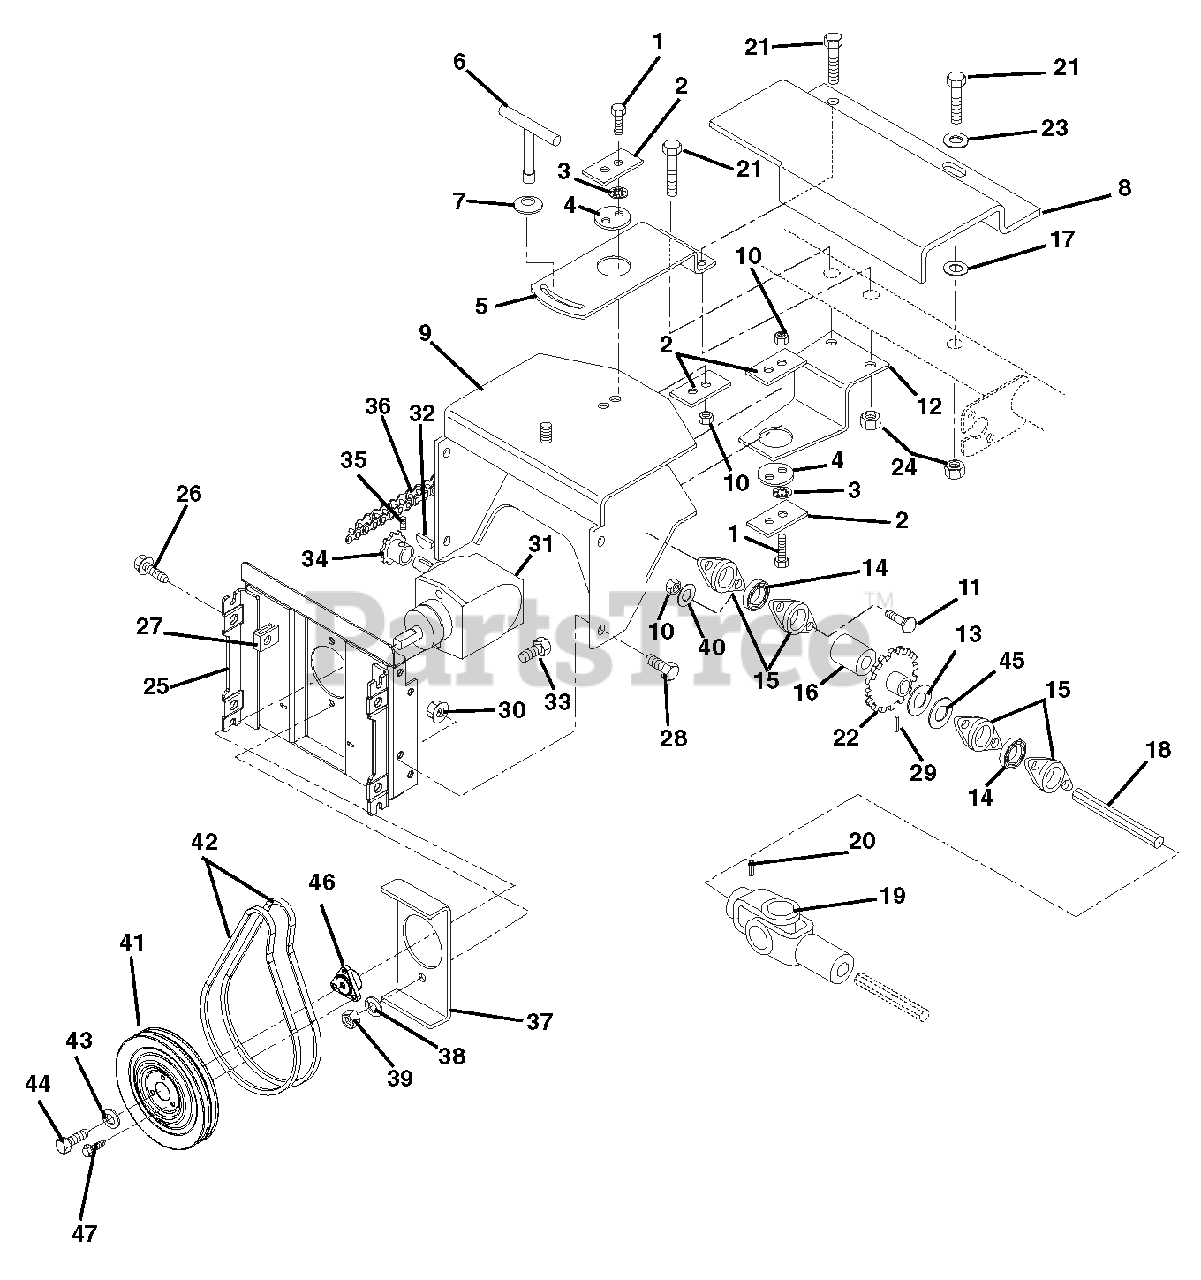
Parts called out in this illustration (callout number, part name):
1	@BLT-HEX .31-18X1.25 GR5 YWZC
2	RETAINER
3	@WSHR-LK-EXT.326X.599X.031YWZC
4	PIVOT CENTER
5	PLATE, TOP MOUNT
6	T-LOCK HANDLE
7	WSHR-BLVL .669X1.535X.138
8	GUARD, SHAFT
9	FRAME, ADAPTOR
10	@NUT-LK-CTR .31-18 YWZC
11	@BLT-RDHDSQNK .31-18X.75 G5YZ
12	PLATE, BOTTOM MOUNT
13	WSHR-FL-STL 1.031X1.625X.188
14	BRG-BALL .884HEXX52MMX1.07
15	BEARING FLANGE
16	SPACER 1.006X1.307X.500
17	WSHR-FL-STL .390X.88X.18 YWZC
19	JOINT, UNIVERSAL
20	PIN-ROLL .188X1.50
21	@BLT-HEX .38-16X3.25 GR5 YWZC
22	SPROCKET
23	@WSHR-FL-STL.406X.812X.065 YWZ
24	@NUT-LK-CTR .38-16 YWZC
25	PLATE, MOUNTING-BROOM
26	BLT-SERHFWH .38-16X.75 YWZC
27	NUT-RTNR .375-16X.37
28	@BLT-HEX .38-16X.75 GR5 YWZC
29	PIN-ROLL .188X1.75
30	@NUT-LK-CTR .38-16 YWZC
31	GEAR BOX ASSEMBLY
32	KEY-WDRF .188X.75X.313 SAE 9
33	@BLT-HEX .38-16X1.25 GR5 YWZC
34	SPROCKET
35	SCR-SET .25-20X.38 SKHCUPNL OH
36	ROLLER CHAIN #41 - 34 PITCHES
37	PLATE, STIFFENER
38	@WSHR-LK .38X.094 REG YWZC
39	@NUT-HEX .38-16 YWZC
40	@WSHR-FL-STL.38X.875X.083 YWZC
41	PULLEY, SPIN FORM DUAL GROOVE
42	V-BELT, HA-RAW EDGE (SET)
43	WSHR-LK .312X.097 HVY YWZC
44	BLT-HEX .31-24X.75 YWZC GR5
45	WSHR-FL-STL 1.03X1.31X.105
46	PULLEY HUB, D-BORE .87 PRO
47	@SCR-TAP .31-18X.50 HWH TR YWZ
